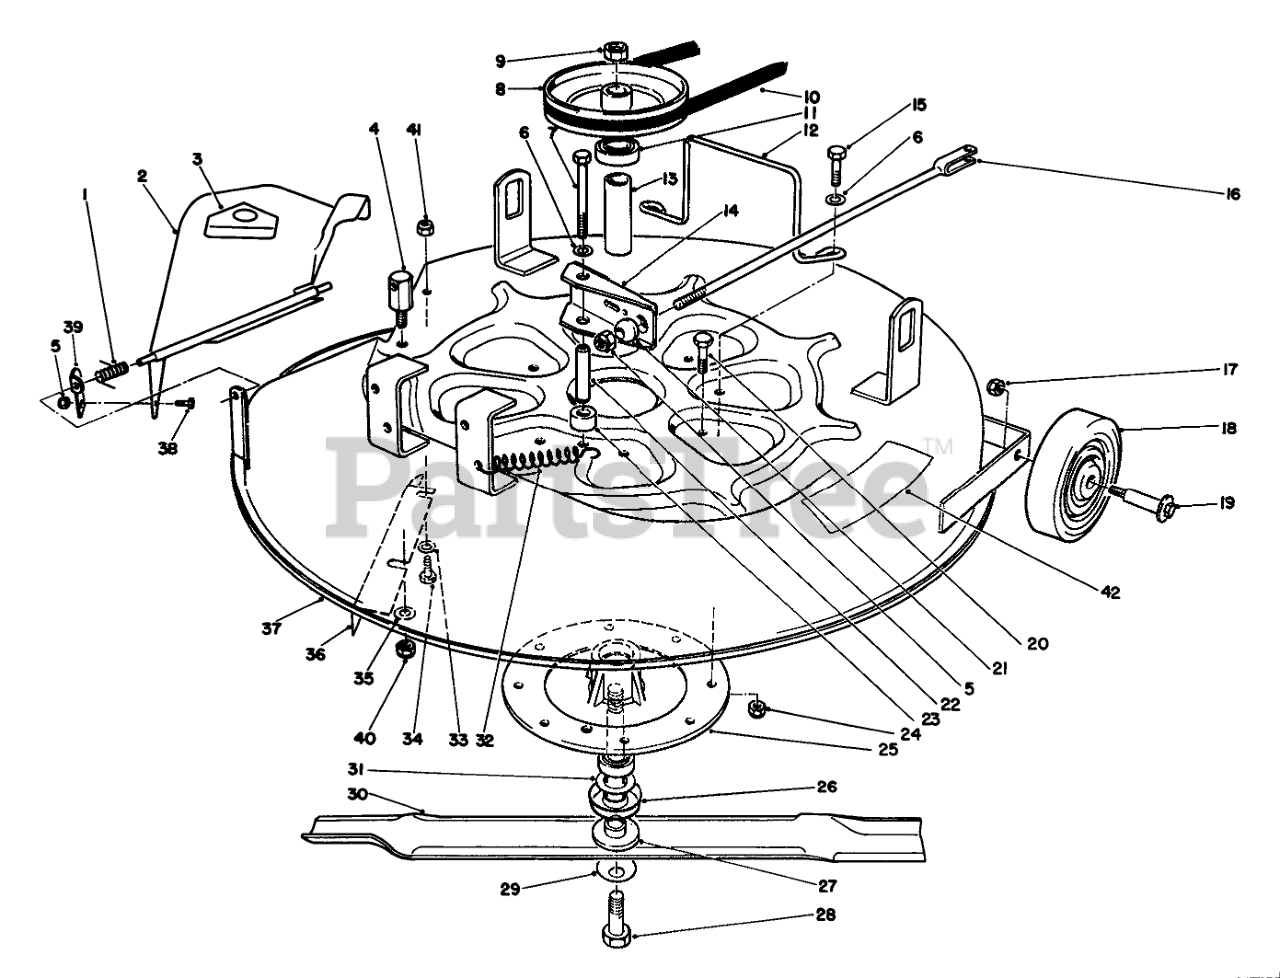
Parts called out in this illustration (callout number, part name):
1	SPRING
2	Deflector (Incl. Ref. #3)
3	DECAL-DANGER
4	POST-PIVOT
5	NUT-HEX
6	WASHER-PLAIN
7	SCREW-HH
8	PULLEY-DECK
9	NUT-HEX
10	V-Belt
11	BEARING-BALL
12	GUIDE-DECK BELT
13	SPACER-BEARING
14	DECK BRAKE ASSEMBLY
15	SCREW-HH
16	DECK BRAKE ROD WA
17	NUT-LOCK, NI
18	WHEEL-DECK
19	BOLT-WHEEL
20	SCREW-HH
21	BALL-SWIVEL, STOP
22	POST-BRAKE MTG
23	SPACER-DECK BRAKE
24	NUT-LOCK, NI
25	CASTING-SPINDLE
26	SHIELD-BEARING
27	SHAFT-SPINDLE
28	SCREW-HH
29	WASHER-BELLEVILLE
30	Blade
31	SPACER
32	SPRING-EXTENSION
33	WASHER-FLAT
34	SCREW-HHF
35	WASHER-FLAT
36	Baffle
37	Deck
38	SCREW-HH
39	Bracket-Detector
40	NUT-LOCK, NI
41	NUT-LOCK, NI
42	DECAL - DANGER
